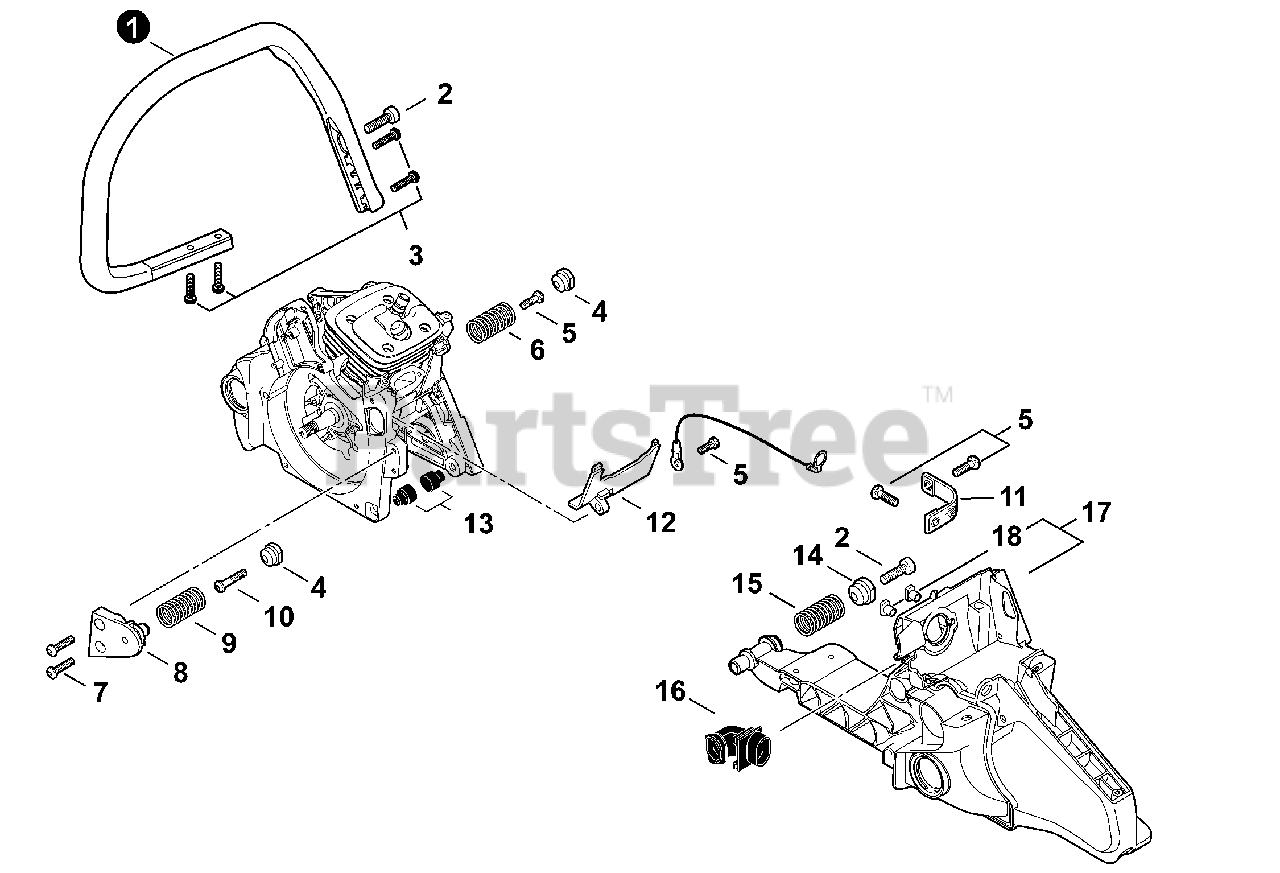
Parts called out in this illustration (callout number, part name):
1	HANDLE, FRONT
2	BOLT, TORX 6×20
3	BOLT, TORX 5×20
4	HOLDER, SPRING Ø14.4
5	BOLT, TORX 5×16
6	SPRING, COMPRESSION Ø17×38.4×2.6
7	BOLT, TORX 5×20
8	HOLDER, SPRING
9	SPRING, COMPRESSION Ø17×36.7×2.6
10	BOLT, TORX 5×25
11	STRAP, SAFETY
12	GUIDE, AIR
13	CUSHION
14	HOLDER, SPRING Ø17
15	SPRING, COMPRESSION Ø20×40×3.3
16	PIPE, AIR INTAKE
17	HANDLE, REAR
